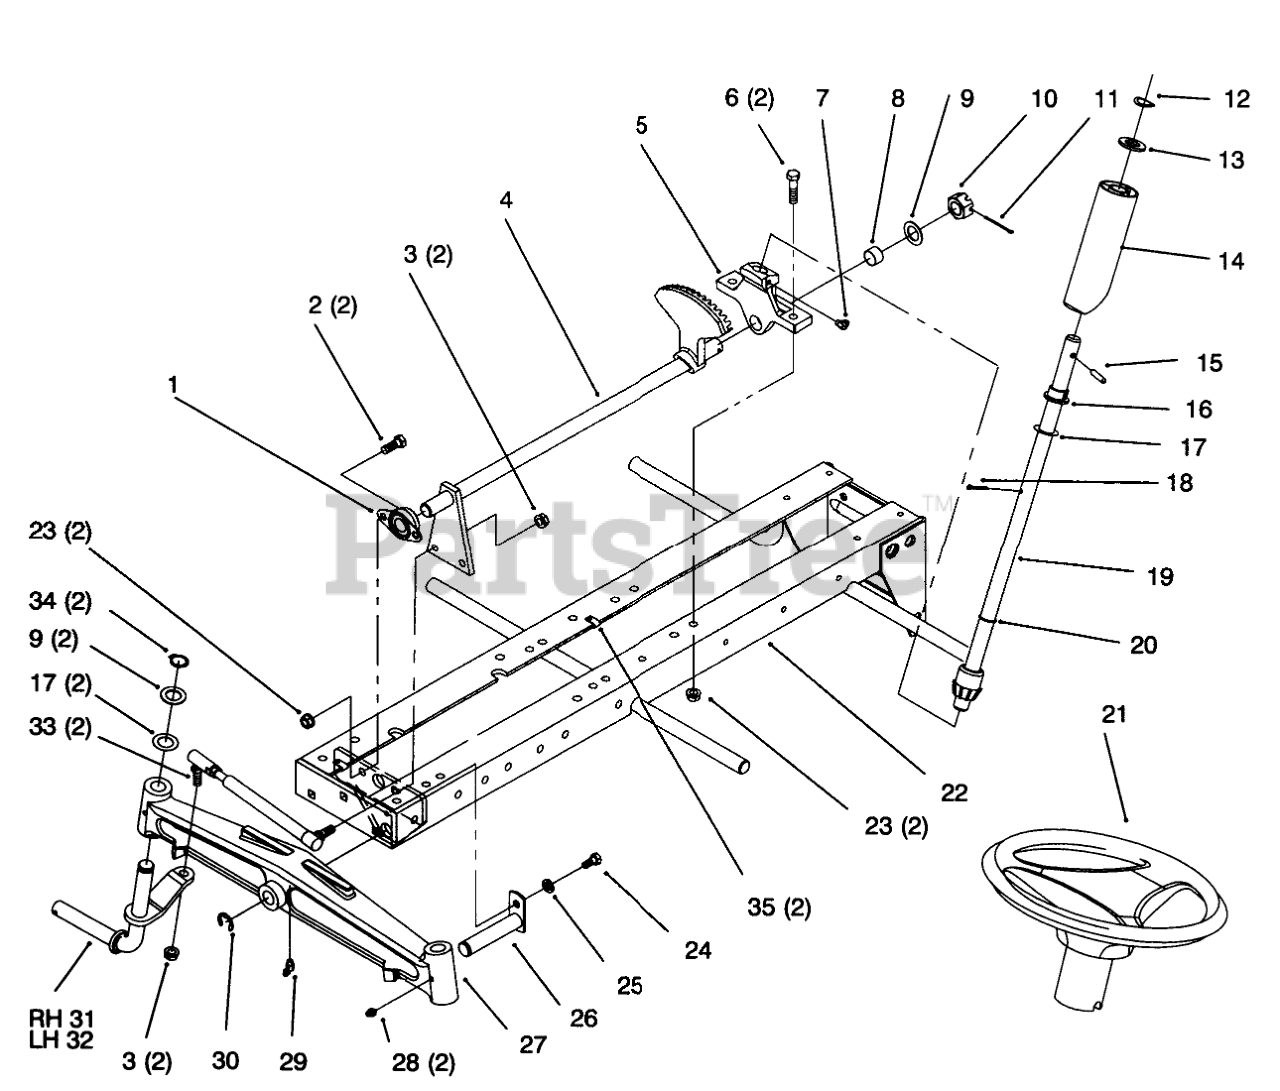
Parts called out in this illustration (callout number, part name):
1	BEARING-FLANGED
2	SCREW-HH
3	NUT-LOCK
4	Shaft
5	Support-Steering
6	SCREW-HH
7	FITTING-GREASE
8	BEARING-BRONZE
9	WASHER
10	NUT-HEX, SLOTTED
11	PIN-COTTER
12	WASHER-BOWED
13	WASHER-FLAT
14	TUBE-STEERING
15	PIN-ROLL
16	BEARING-FLANGED
17	PIN-COTTER
17	WASHER-SHIM
19	STEERING SHAFT ASM
20	O-RING
21	WHEEL - STEERING 15"
22	Frame
23	NUT-LOCK, NI
24	SCREW-HH
25	WASHER-LOCK
26	PIN AND PLATE ASM
27	AXLE-FRONT
28	FITTING-GREASE
30	E-RING
31	LH SPINDLE ASM
32	RH SPINDLE WA
33	ASM-Rod
34	RING-RETAINING
35	CLIP-WIRE
